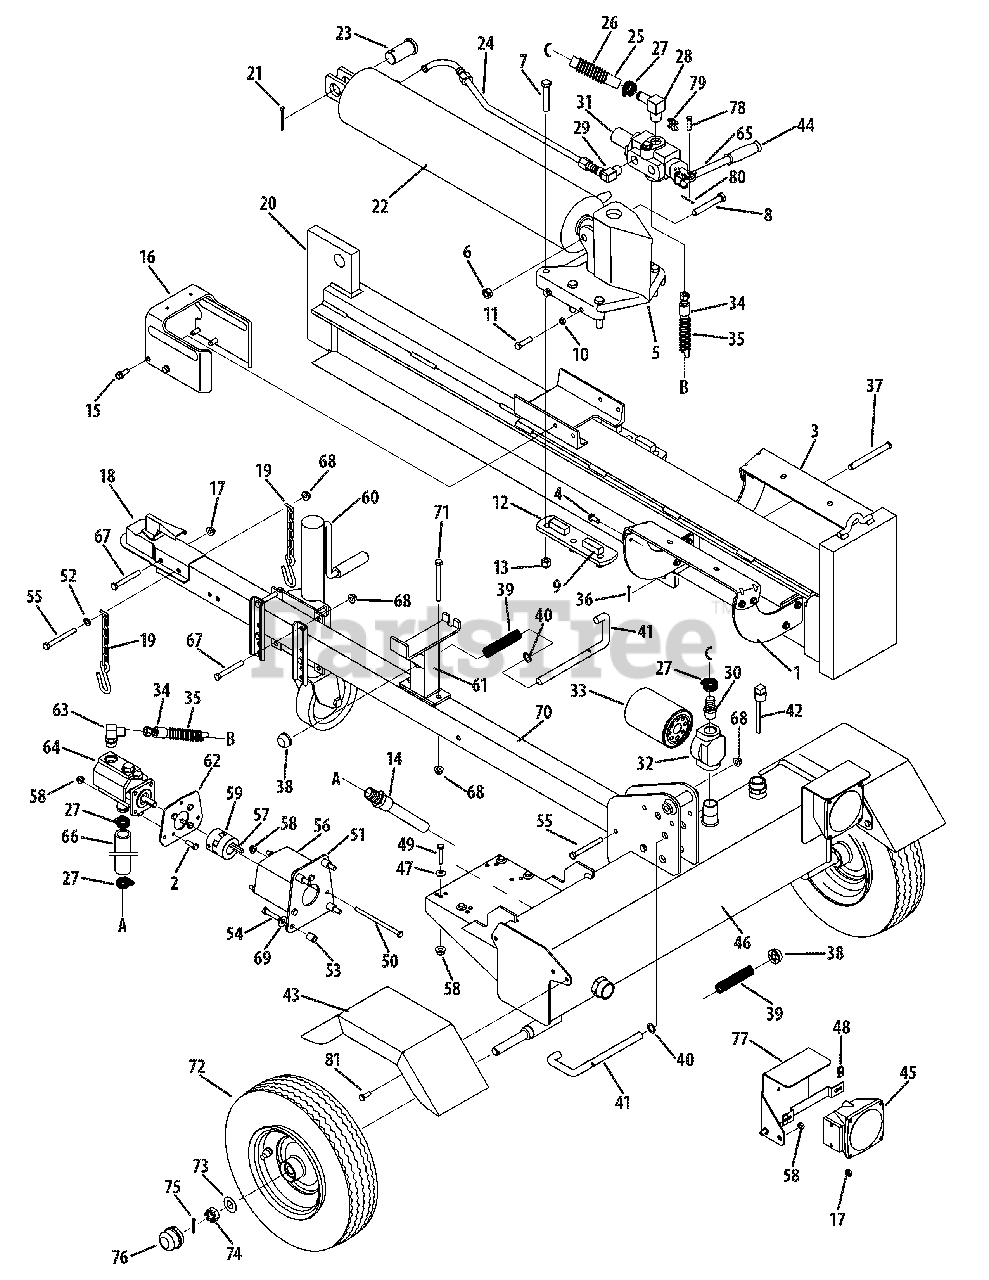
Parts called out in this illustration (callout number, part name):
1	Log Tray Bracket
2	Hex Screw, 5/16-18 x 1.00
3	Log Tray Bracket
4	TT Screw, 5/16-18 x .750
5	Wedge Assembly
6	Lock Nut, 1/2-13
7	Hex Cap Screw, 1/2-20 x 2.75
8	Hex Cap Screw, 1/2-13 x 3.25
9	Adjustable Gib
10	Hex Jam Nut, 3/8 -24
11	Hex Cap Screw, 3/8 -24 x 1.5
12	Back Plate
13	Hex Lock Nut,1/2-20
14	Inlet Filter
15	Hex Washer Screw, 3/8-16 x 1.0
17	Jam Nut, 3/8-16
18	2-inch Hitch Coupler
20	Beam Assembly
21	Cotter Pin
22	Hydraulic Cylinder 31/33 Ton
22	Kit Seal 5.0" for XINGHUI cylinder 718-0313A
22	Kit Seal 5.0" for ENERGY cylinder 718-0313A
23	Clevis Pin
24	Hydraulic Tube
25	Return Hose, 3/4" ID x 44"
26	Hose Guard
27	Hose Clamp, 5/8"
28	Return Elbow
29	90 Degree Solid Male Adapter
30	3/4" Hose Adapter
31	Control Valve
32	Filter Housing
33	Oil Filter
34	High Pressure Hydraulic Hose
35	Hose Guard
36	Cotter Pin, 1/8 "
37	Hinge Pin, 1/2x 4.8" Lg.
39	Compression Spring 4"
40	Flat Washer, .635 ID x .93 OD
41	Locking Rod
42	Vented Dipstick
45	Tail Light Assembly
48	Tin Nut Clip, 1/4-20
49	Hex Cap Screw, 5/16-18 x 1.75
50	Hex Cap Screw, 5/16-18 x 5.50
51	Front Support Bracket Coupling
52	Flat Washer, .375 x .738 x .063
53	Spacer, .385 x .623 x .750
54	Hex Cap Screw, 3/8 -16 x 1.75
55	Hex Cap Screw, 3/8-16 x 3.50
56	Coupling Shield
58	Hex Flange Lock Nut, 5/16-18
59	Flex Coupling
60	Adjustable Jack Stand
61	Support Beam Assembly
62	Rear Coupling Support Bracket
63	Adapter, 7/8-14
65	Hydraulic Valve Control
66	Suction Hose
67	Hex Cap Screw, 3/8-16 x 3.0
68	Flange Lock Nut, 3/8-16
69	Lock Washer, 3/8
71	Hex Cap Screw, 3/8-16 x 4.0
72	Wheel Assembly
73	Flat Washer, .76" ID x 1.5" OD
74	Slotted Nut, 3/4-16
75	Cotter Pin, 5/32" x 1-1/4"
77	Light Bracket Assembly LH
77	Light Bracket RH
78	Clevis Pin
79	Valve Handle Link
80	Cotter Pin
81	TT Screw, 5/16-18 x .875
